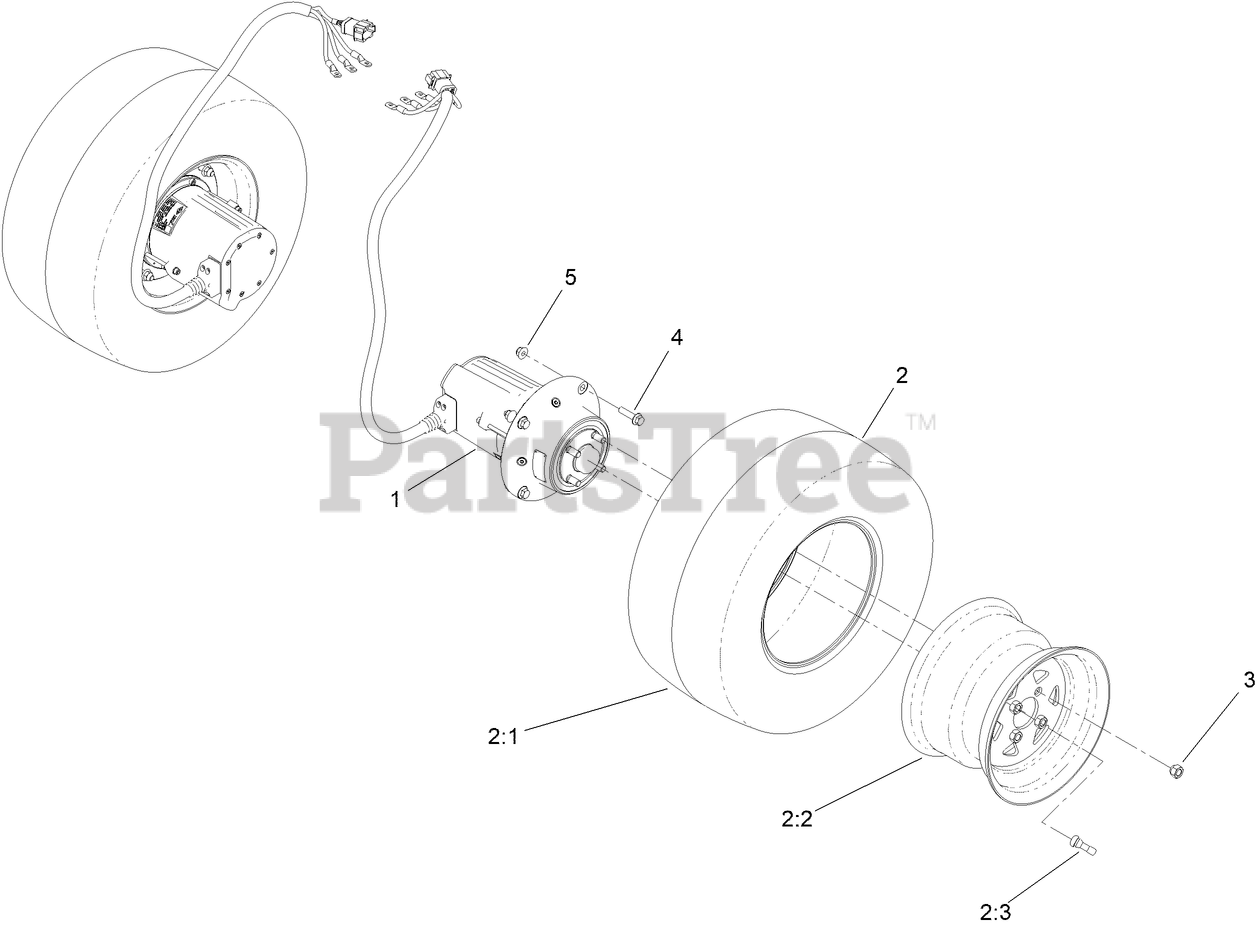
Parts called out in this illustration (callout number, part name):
1	MOTOR/GEARBOX ASM-48V,
2	WHEEL AND TIRE ASM
2:1	RIM-10 IN
3	NUT-WHEEL
4	SCREW-HHF
5	NUT-HF, NI
